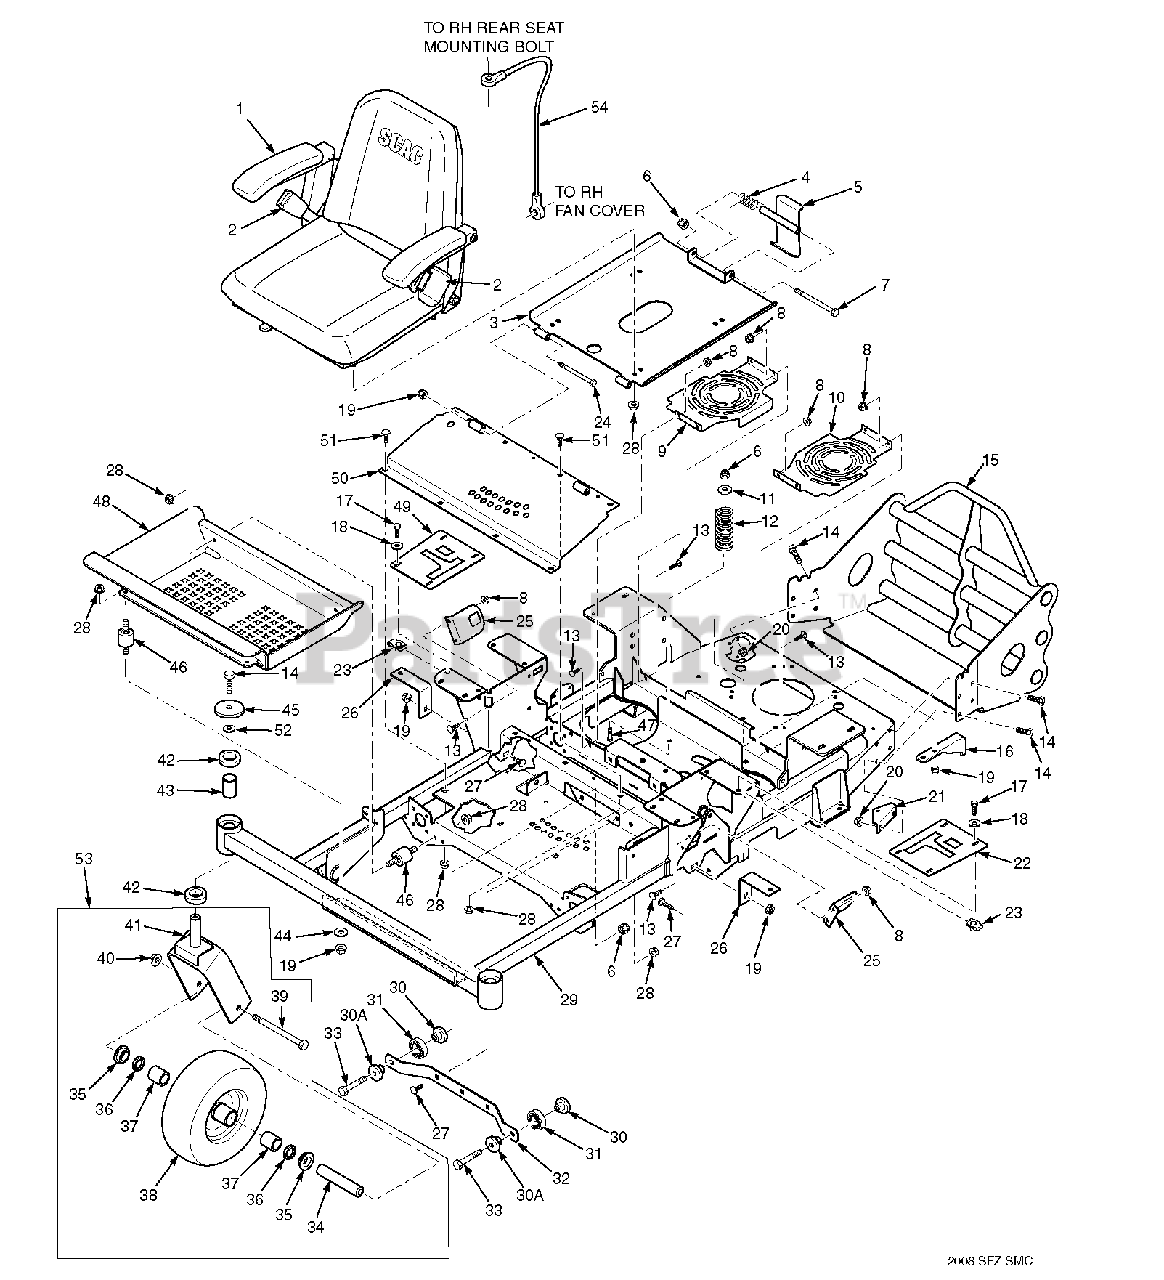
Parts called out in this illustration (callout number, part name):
1	Seat Assembly
2	Seat Belt Assembly, Retractable
3	Seat Base w/Decal
4	Spring, Seat Latch
5	Seat Latch
6	Nut, Elastic Stop 3/8-16
7	Bolt, Hex Head 3/8-16 x 6"
8	Nut, Serrated Flange 1/4-20
9	Cover, Fan RH
10	Cover, Fan LH
11	Flatwasher, 3/8-.391 x .938 x .105
12	Spring, Seat
13	Bolt, Carriage 1/4-20 x 1"
14	Bolt, Hex Head 3/8-16 x 1"
15	Rear Bumper
16	Bracket, Anti-Rotation
17	Bolt, Hex Head 1/4-20 x 1"
18	Flatwasher, 1/4-.312 x .750 x .065
19	Nut, Elastic Stop 5/16-18
20	Nut, Serrated Flange 3/8-16
21	Bracket, Dump Valve
22	Control Plate LH
23	U-Nut 1/4-20
24	Bolt, Hex Head 5/16-18 x 3-3/4"
25	Bracket, Switch Mount
26	Bracket, Tank Mount
27	Bolt, Carriage 5/16-18 x 3/4"
28	Nut, Serrated Flange 5/16-18
29	Main Frame w/Decals
30	Spacer, Bearing
30A	Spacer, Bearing
31	Bearing
32	Support, Deck Guide
33	Bolt, Hex Head 3/8-16 x 1-3/4"
33	Bolt, Hex Head 3/8-16 x 2-1/2"
34	Sleeve, Front Caster Wheel
35	Bearing
36	Seal, 1 x 1.375 x .25
37	Bearing
38	Caster Wheel Assembly
39	Bolt, Hex Head 1/2-13 x 6-1/2"
40	Nut, Elastic Stop 1/2-13
41	Yoke, Caster Wheel
42	Bearing
43	Spacer, Caster Bearing
44	Flatwasher, 5/16-.375 x .875 x .083
45	Flatwasher, 3/8-.406 x 2.25 x .188
46	Rubber Isolator
47	Bolt, Carriage 3/8-16 x 1-1/4"
48	Footplate Weldment
49	Control Plate RH
50	Weldment, Deck Lift Cover
51	Bolt, Carriage 5/16-18 x 1/2'
52	Flatwasher, 7/16-.50 x 1.250 x .083
53	Caster Wheel Assembly w/Yoke
54	Cable, Seat Stop
